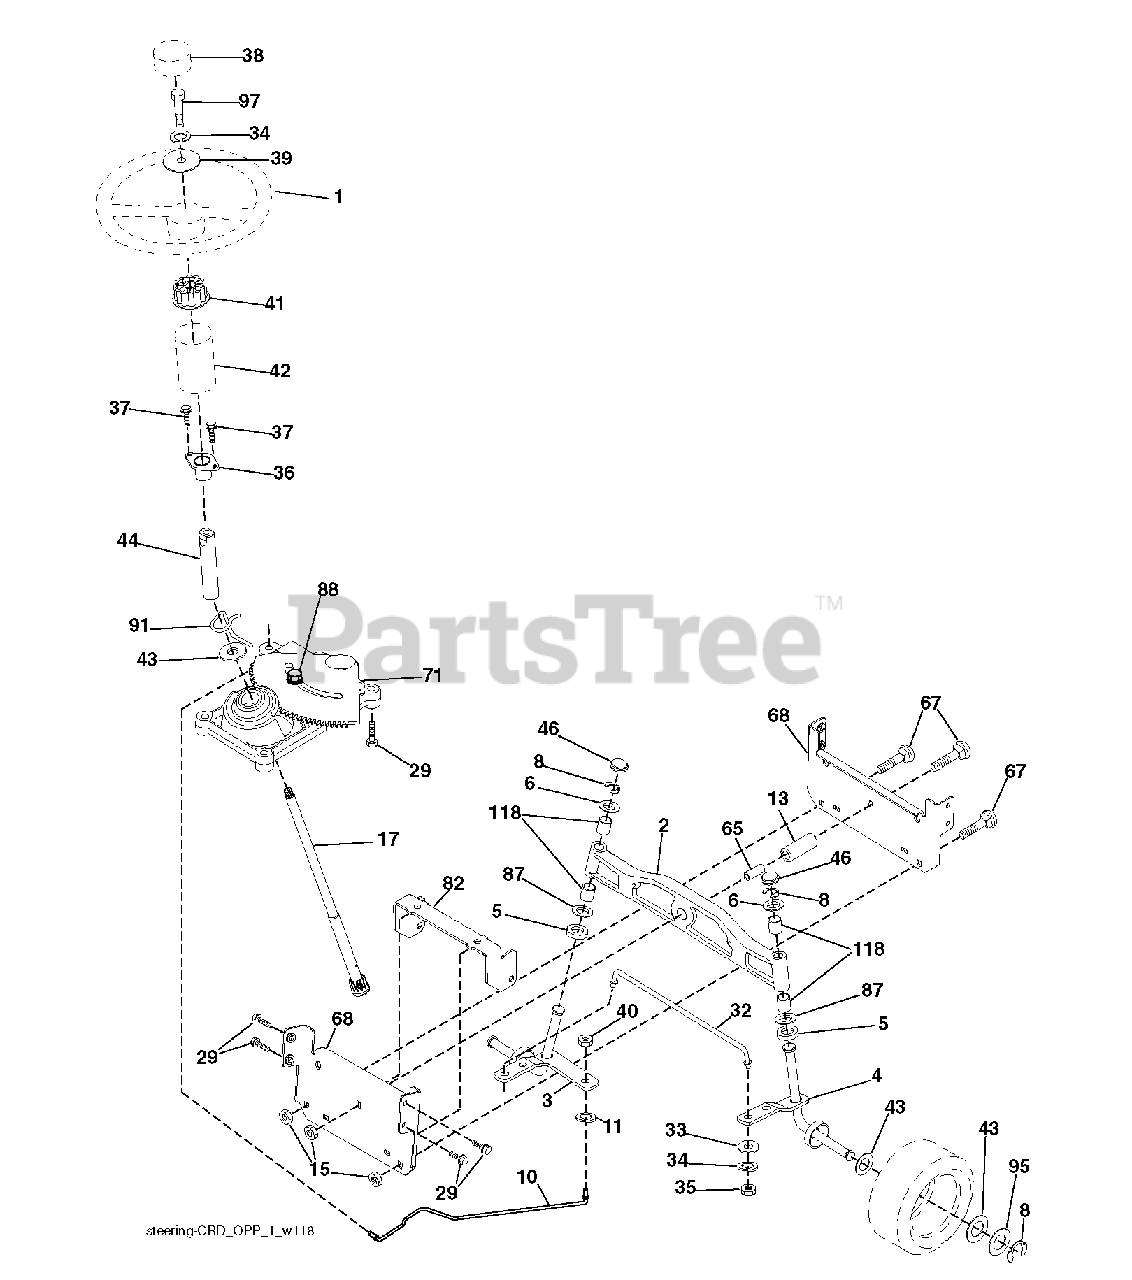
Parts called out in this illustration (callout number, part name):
1	WHEEL.STEERING.PREM.2.BLK
2	AXLE ASSY FRONT
3	SPINDLE.ASM.LH.15"TIRES
4	SPINDLE.ASM.RH.15"TIRES
8	RING CLIP
10	DRAGLINK.15".TIRES.2001
11	WASHER, LOCK 3/8
13	TUBE, PIVOT AXLE
15	NUT
17	SHAFT STEERING SPLINE
29	SCREW, 3/8-16X3/4
32	ROD.ASM.TIE.BALL.JOINT.NOVAN
33	WASHER M
34	LOCKWASHER
35	NUT, CROWNLOCK
36	BUSHING, STEERING
38	INSERT.CAP.STRG.WH.BLACK
39	WASHER.11/32
40	NUT CROWNLOCK 3/8-24
41	ADAPTER, WHEEL STNG..
42	BOOT.STEERING.SHAFT.BLACK
44	SHAFT.EXTEN.STRG.SPLINE
46	CAP.SPINDLE
65	SPACER.BRACE.AXLE
67	BOLT CARRIAGE
68	BRACE.AXLE.15"TIRES
71	STEERING ASM
82	BRACKET.SUSP.CHASSIS.FRONT.15
87	WASHER, FLAT .781 X 1 1/2"
88	BOLT, SHOULDER 7/16-20
91	CLIP.STEERING
95	WASHER.HARDENED
118	BUSHING, AXLE CAST
